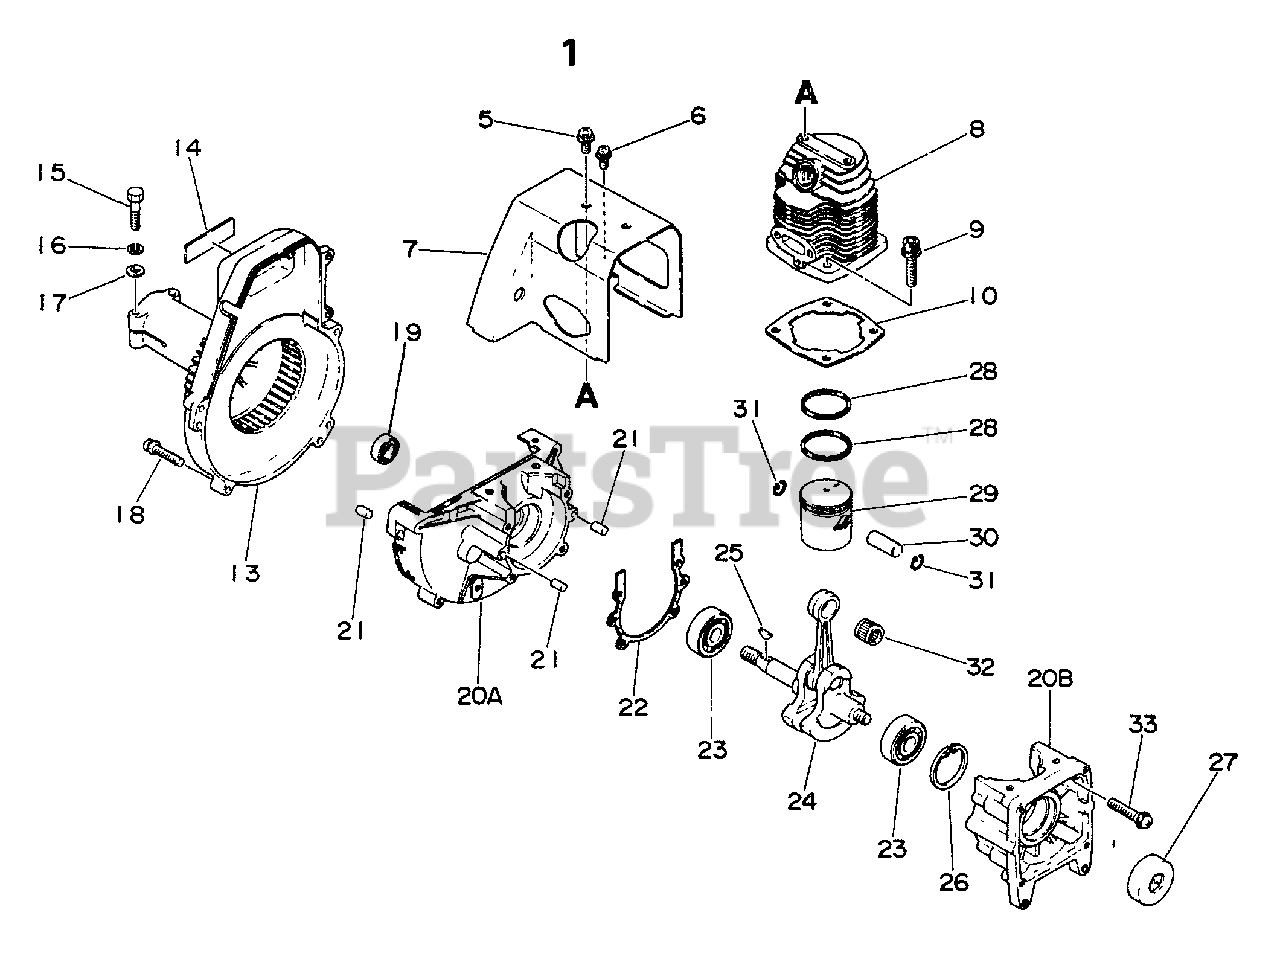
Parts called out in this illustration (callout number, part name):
5	SCREW 5×10
6	SCREW 4×10
7	COVER, ENGINE
8	CYLINDER
9	BOLT 5×20
10	GASKET, CYLINDER
13	COVER, FAN
14	LABEL
15	BOLT - 5×25
16	WASHER, SPRING 5
17	WASHER, FLAT 5.5×10×0.8
18	SCREW 5×25
19	SEAL, OIL
20	CRANKCASE KIT
20A	CRANKCASE KIT
20B	CRANKCASE KIT
21	PIN, LOCATING 5×10
22	GASKET, CRANKCASE
23	BEARING, BALL 6202
24	CRANKSHAFT
26	RING, SNAP 35
27	SEAL, OIL 18
28	RING, PISTON
29	PISTON
30	PIN, PISTON
31	RING, SNAP 8
32	BEARING, NEEDLE
33	SCREW 5×30
